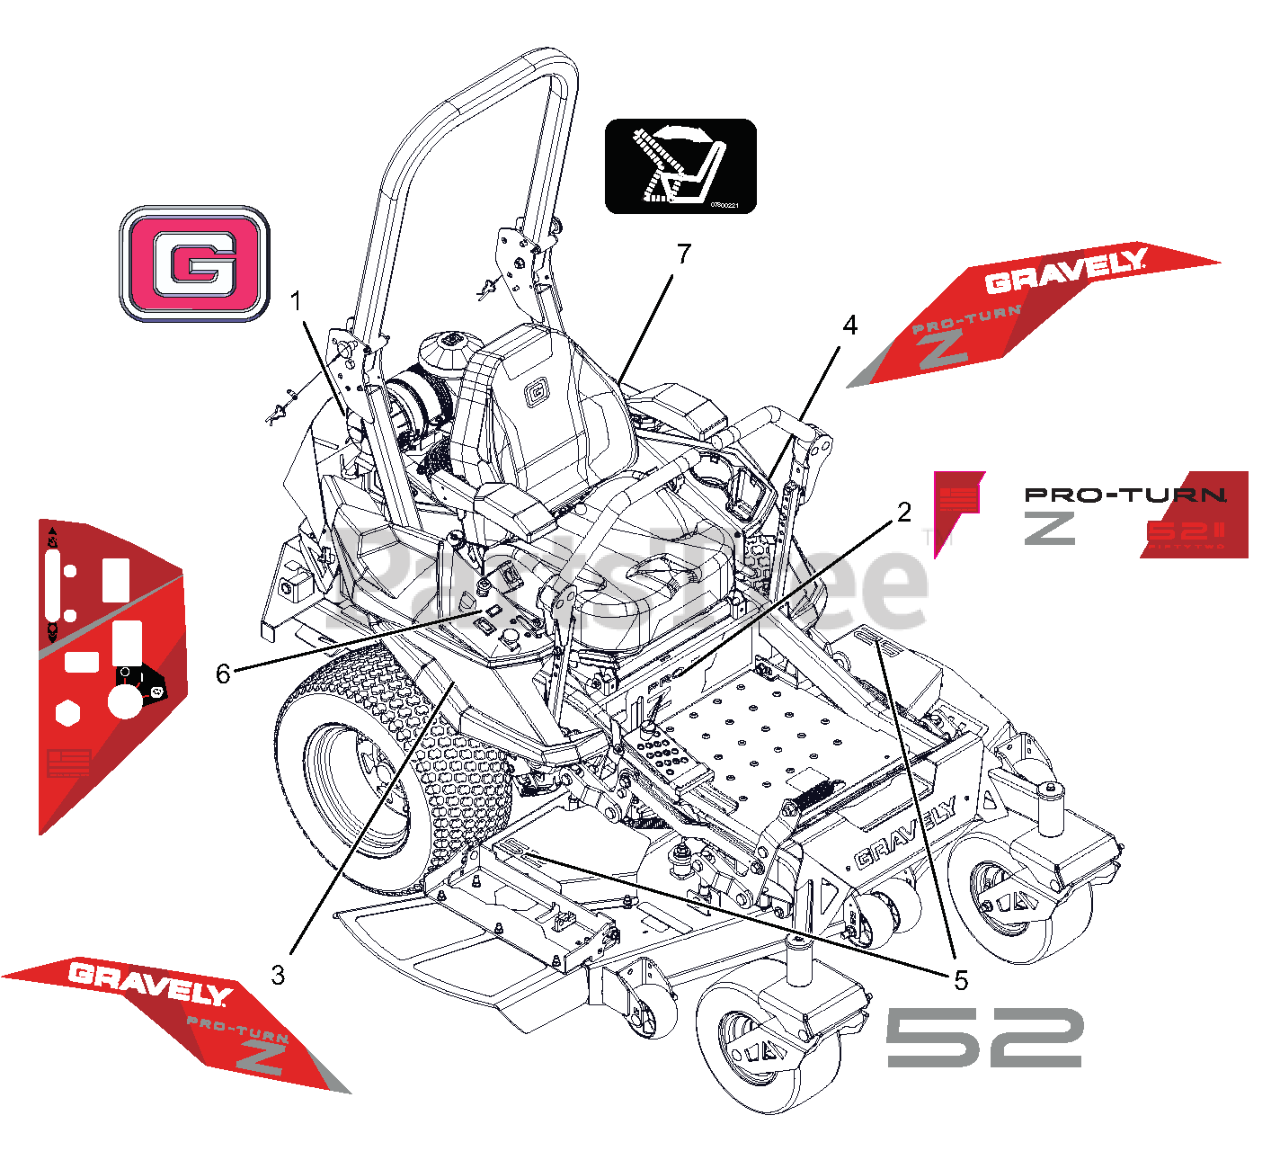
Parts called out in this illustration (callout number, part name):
1	DECAL, DECK - 60
2	DECAL - SEAT RELEASE
3	DECAL, FENDER RH - PTZ
4	DECAL, FENDER LH - PTZ
5	DECAL, DECK - 60
6	DECAL, CONTROL PANEL
7	DECAL, PTZ - 60
